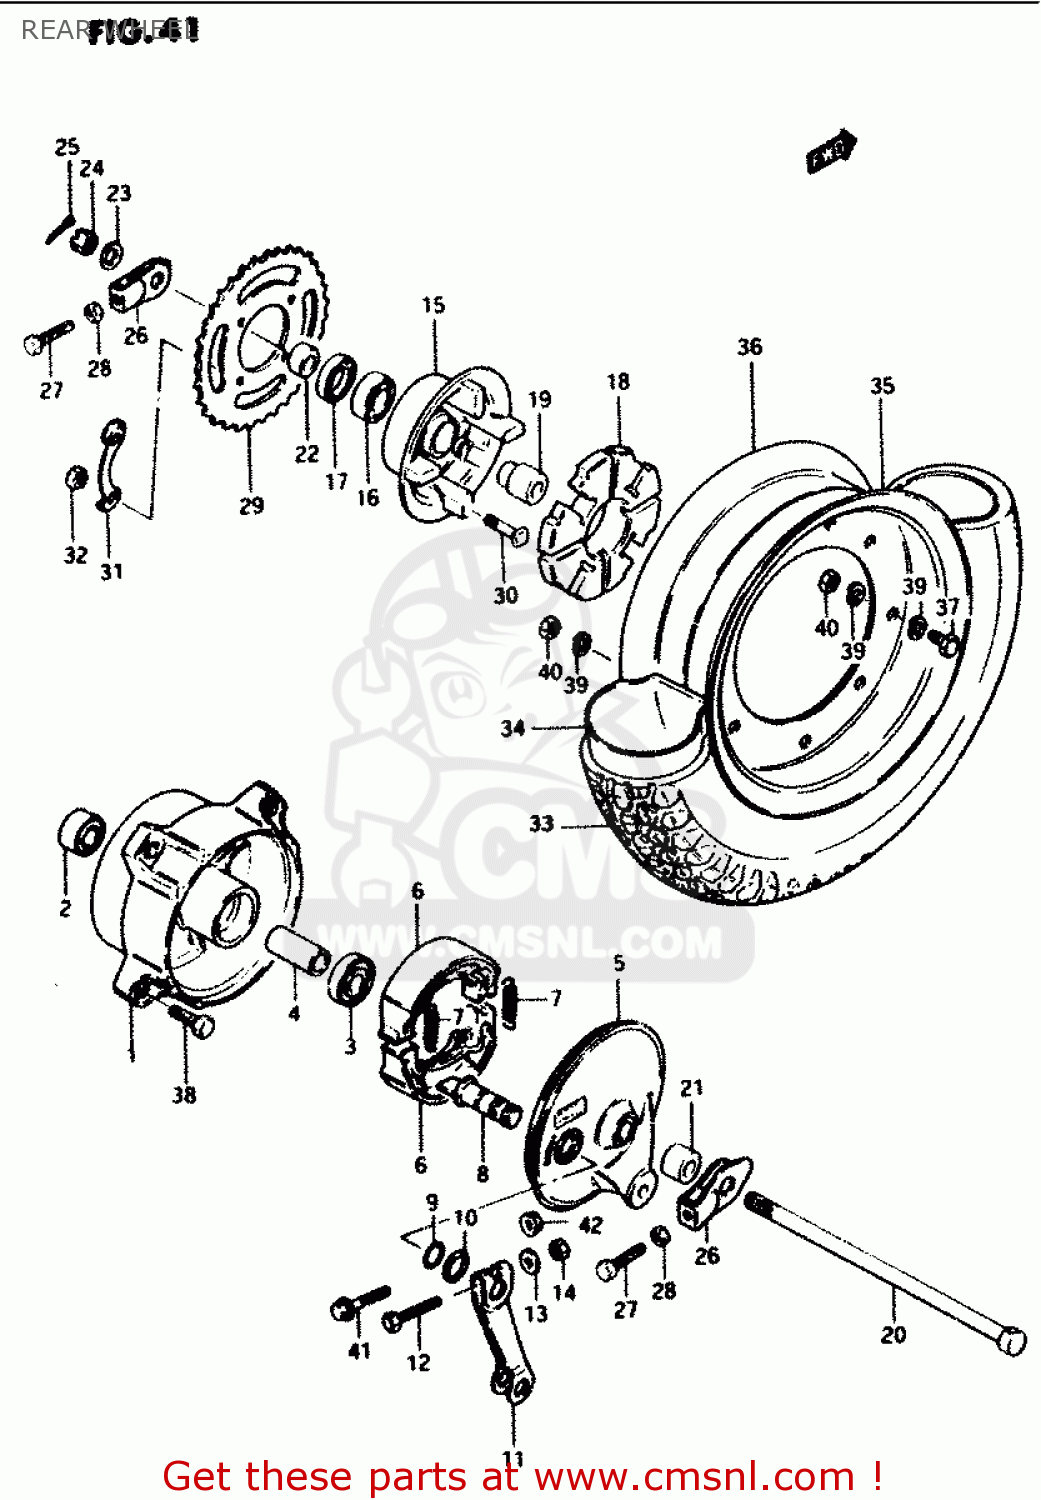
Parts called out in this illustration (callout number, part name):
1	HUB,RR WHEEL
2	BEARING
3	BEARING
4	SPACER(12.6X19X68)
5	PANEL,REAR BRAKE ANCHOR
6	SHOE,BRAKE
7	SPRING(L:35.8)
8	CAM,FRONT BRAKE
9	O-RING (D:2.4 ID:13.8)
10	WASHER (14.5X22X1.6)
11	LEVER,REAR BRAKE CAM
12	BOLT(6X33)
13	WASHER
14	NUT
15	DRUM,REAR SPROCKET MOUNT
16	BEARING
17	SEAL OIL(25X40X6)
18	CUSHION,REAR DRUM
19	RETAINER,RR SPROCKET DRUM
20	AXLE, REAR
21	SPACER(12.2X22X14)
22	SPACER
23	WASHER
24	NUT
25	COTTER PIN
26	ADJUSTER,CHAIN,R
27	BOLT(6X38)
28	NUT
29	SPROCKET,REAR
30	BOLT(8X33.5)
31	WASHER
32	NUT
33	TIRE, REAR (3.50-8) IRC
34	TUBE ASSY,WHL I
35	RIM,WHEEL,R(8X2.50C)
36	RIM,WHEEL,L
37	BOLT,8X16
38	BOLT
39	WASHER,LOCK
40	NUT
41	BOLT(6X32)
42	NUT
